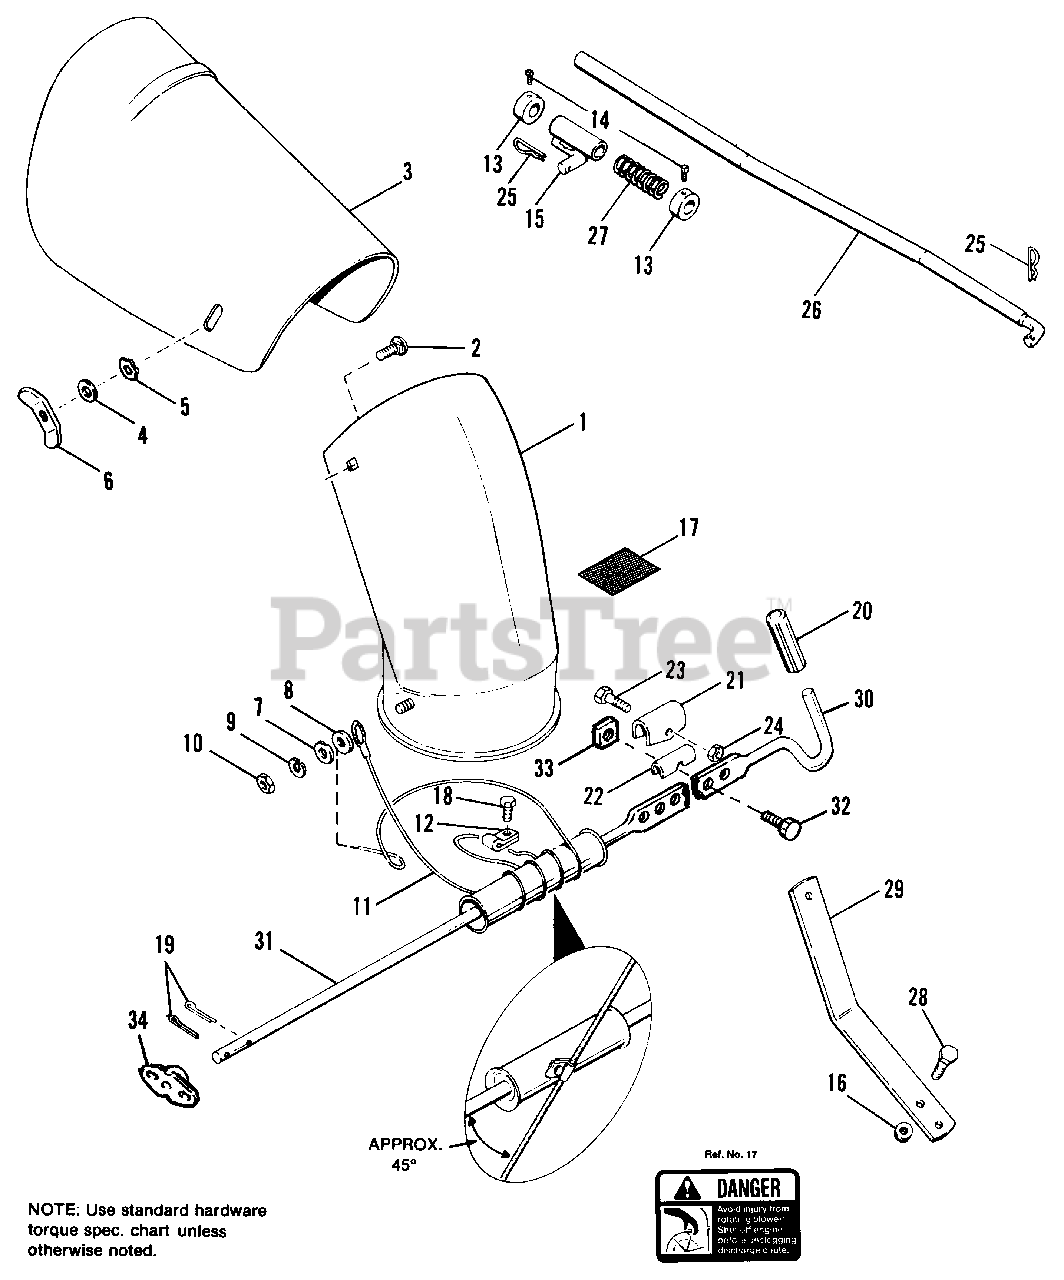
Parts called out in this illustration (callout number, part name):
1	SPOUT ASSY.
2	CARRIAGE BOLT, 5/16-18 x 3/4
3	EXTENSION, Spout
4	WASHER, Plain, 3/8
5	LOCKWASHER, Dished, 3/8
6	NUT, Wing, 5/16-18
7	WASHER, Cup
8	WASHER, Plain, 1/4
9	LOCKWASHER, 5/16
10	NUT, Hex, Full, 5/16-18
11	CABLE ASSY.
13	COLLAR, Set
14	SETSCREW, 5/16-18 x 1/2
15	GUIDE ASSY., Rod
16	NUT, Flange, 3/8
17	DECAL, Danger
18	SCREW, Taptite, 1/4-20 x 3/8
19	PIN, Cotter, 3/32 x 5/8
20	GRIP, Handle
22	LINER, Guide
23	CAPSCREW, Hex, 5/16-18 x 1-1/4
24	LOCKNUT, Hex, Full, 5/16-18
25	CLIP, Spring
26	ROD, Front Lift
28	CAPSCREW, Hex, 3/8-16 x 1
29	ARM SUPPORT
30	HANDLE, Spout Control
31	ROD ASSY., Spout Control
32	CAPSCREW, Hex Hd., 5/16-18 x 7/8
33	NUT, Hex, Flange Lock, 5/16-18
34	BEARING, Self-Align, 1/2 I.D.
